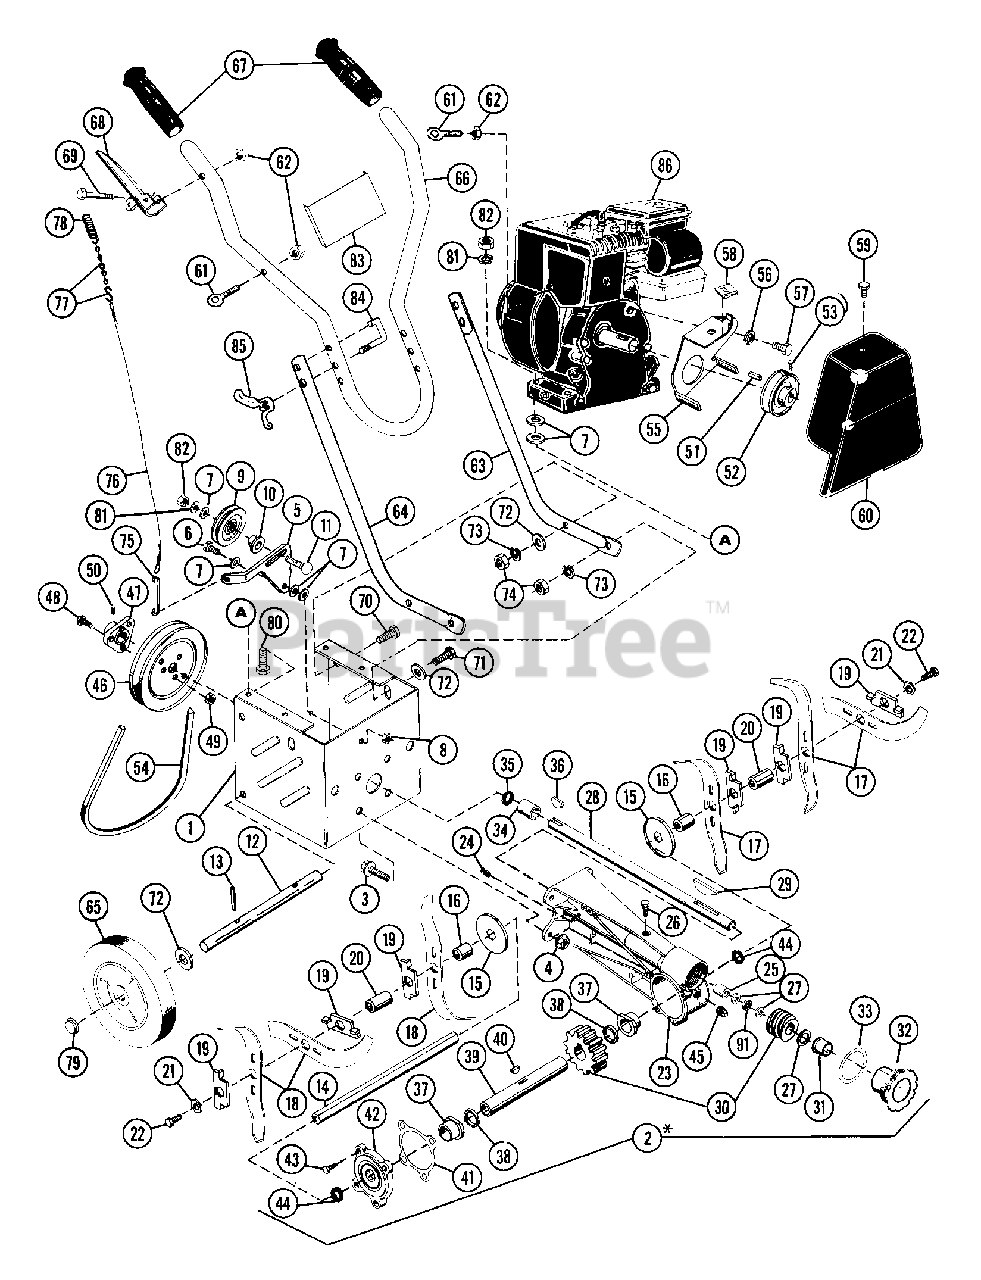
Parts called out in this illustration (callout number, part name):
1	FRAME
2	GEAR CASE - ALUMINUM
3	SCREW - FLG WIZ LOCK HH PL
4	NUT-LK-FLG .375-16 PL
5	IDLER BRACKET
6	BLT-HEX .31-18X1.00 PL GR 2
7	WSHR-FL-STL .38X.875X.083 PL
8	NUT-LK .312-18 GR A PL
9	IDLER
10	SPCR, BRG .315X.50X.688X.281
11	BLT-RDHDSQNK .31-18X1.38SHT PL
12	AXLE ROD
13	PIN-ROLL .125X.75
14	HEX TINE SHAFT
15	DUST CUP
16	SPACER .747X1.002X1.250
17	LEFT HAND TINE
18	RIGHT HAND TINE
19	TINE RETAINER
20	SPACER .747X1.002X1.562
21	WSHR-LK .375X.130
22	BLT-HEX .38-24X.75 GR5
23	GEARCASE - ALUMINUM
24	BREATHER
25	BSHG-SLV .750X1.000X.750
26	BLT-SCRHFWH .38-16X.50 PL
27	WSHR-HDND-THRST .755X1.40X.062
28	WORM SHAFT
29	KEY-FTHR .188X1.38X.188
30	WORM & WORM GEAR SERVICE ASSEM
31	BSHG-FLG .750X1.000X.750X1.132
32	ADJUSTMENT PLUG
34	BSHG-SLV .750X1.000X1.000
35	SEAL .750X1.000X.125
36	KEY-WDRF .188X.875X.375 SAE11
37	BSHG-FLG 1.000X1.25X.75X1.50
38	WSHR-HRD-THRS 1.007X1.542X.062
39	SUB SHAFT
40	KEY-WDRF .188X.625X.25 SAE 61
43	BLT-SERHFWH .31-18X.62 PL
44	SEAL 1.000X1.980X.375
45	PIPE PLUG
47	HUB
48	BLT-SERRDHD SL .31-18X.75 YZ
49	NUT-FLG. .312-18 PL
50	SCR-SET .32-18X.38 SKHCUPNL OH
51	KEY-SQ .188X1.0X.188 SAE 8630
52	ENGINE SHEAVE
53	SET SCREW
54	V-BELT, 4L-RAW EDGE
55	BELT FINGER & COVER BRACKET
56	WSHR-LK .500X.151 HVY PL
57	BLT-HEX .75-16X2.50 PL GR5
58	NUT-SPEED U-TYPE .312-18
59	BLT-HEX .31-18X.50 PL GR2
60	BELT COVER
61	ROD HANGER EYEBOLT
62	NUT-LK-CTR .250-20 PL
63	L H LOWER HANDLEBAR
64	R H LOWER HANDLEBAR
65	TIRE 8X1.75
66	UPPER HANDLEBAR
67	GRIP
68	CLUTCH HANDLE
69	BLT-HEX .25-20X1.50 PL GR5
70	BLT-HEX .38-16X1.75 PL GR2
71	BLT-HEX .38-16X1.00 PL
72	WSHR-FL-STL.406X.812X.065PL
73	WSHR-LK .375X.115 HVY PL
74	NUT-HEX .375-16
76	CLUTCH CABLE
77	CHAIN & CONNECTOR
78	SG-TENS .092X.69X1.75 WLD 54
79	CAP, 3/8 ROD YWZC
80	BLT-HEX .31-18X1.75 PL GR2
81	WSHR-LK .312X.097 PL HVY
82	NUT-HEX .312-18
83	NAME PLATE
85	WING NUT, .312-18
91	BRG-N THRST .754X1.24X.078
